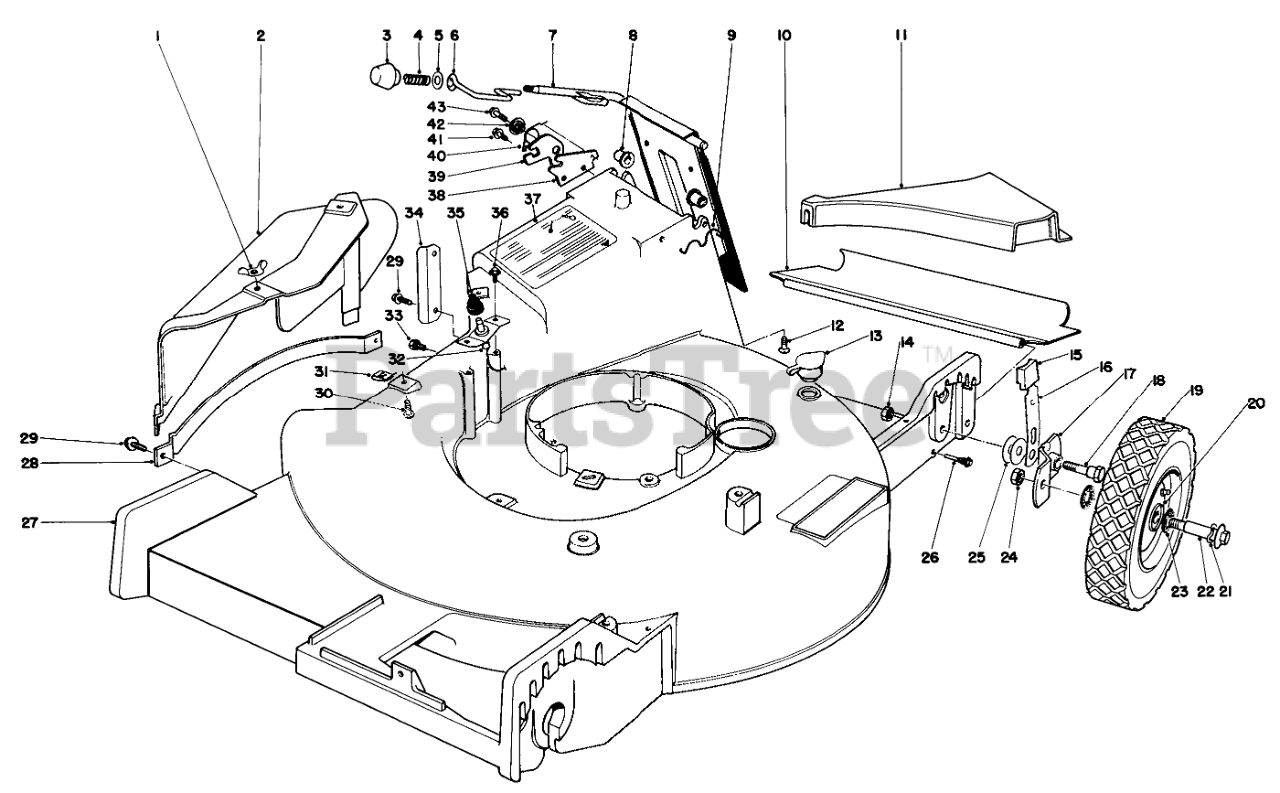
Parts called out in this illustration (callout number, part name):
1	NUT-WING SPECL
2	DEFLECTOR
4	COMPRESSION SPRING
5	WASHER
6	DOOR LATCH
7	Door Handle
8	BUSHING-NYLON
9	Door Retainer
10	REAR SAFETY SHIELD
11	REAR INSERT
12	SCREW-HH
13	WASHOUT PLUG
14	Nut
15	Knob
16	SPRING ARM ASM
17	PIVOT ARM ASM A
18	PIVOT SCREW
19	Wheel & Tire Assembly (Incl. Ref. #20)
20	BEARING-BALL
21	SPRING WASHER
23	FELT WASHER
24	Nut
25	WASHER-PIVOT
26	SAFTEY SHIELD SCREW
27	Housing
28	Bar Safety
29	SCREW
32	Deflector Switch (Incl. Ref. #35)(Model 20506)
33	SCREW THD 1/4 20 5/8
34	Clip Retaining
35	Boot Switch
37	Decal-Caution
38	DOOR LATCH PLATE
39	Latch Safety
40	TORSION SPRING
41	SCREW-HWH
42	Latch Spacer
43	Screw
